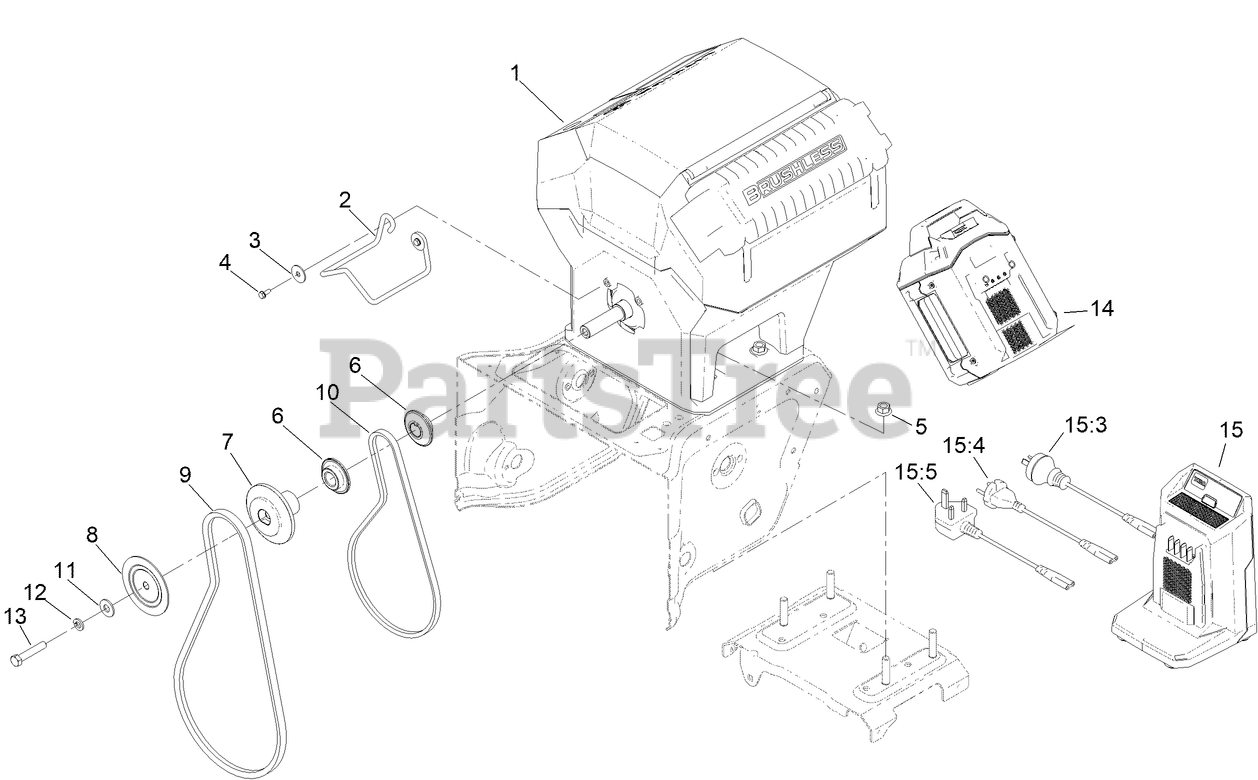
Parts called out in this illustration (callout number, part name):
1	POWERHEAD-60V
2	GUIDE-BELT
3	WASHER-FLAT
4	SCREW-HWH, THD ROLL
5	NUT-LOCK
6	PULLEY-ENGINE, TRACTION
7	PULLEY-AUGER, REAR
8	PULLEY-AUGER, FRONT
9	BELT-V
10	BELT-V
11	WASHER-PLAIN
12	WASHER-LOCK
13	SCREW-HH
14	60V 7.5AH BATTERY CE
15	CHARGER, RAPID 60V
15:3	CORD-CHARGER, AU/NZ
15:4	CORD-CHARGER, CE
15:5	CORD-CHARGER, UK
